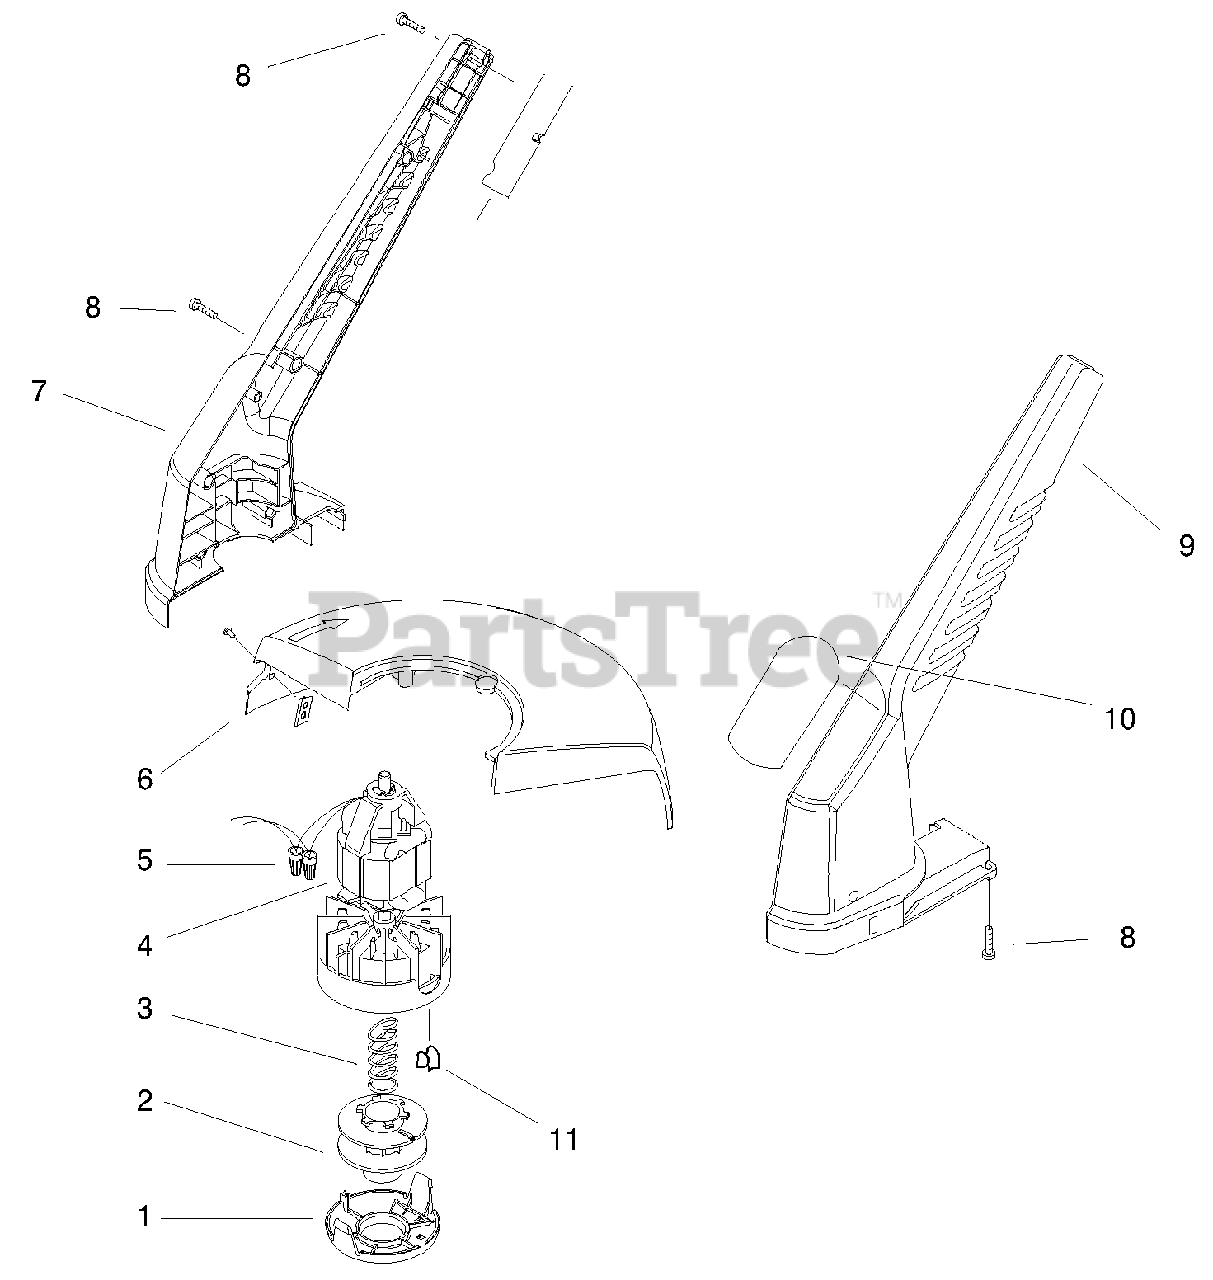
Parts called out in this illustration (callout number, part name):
2	Spool-Large
3	Spring-Compression
4	ASM-Motor,Drum-ervice
5	Connector-Wire Nut
6	Shield ASM-Service
7	Housing-RH (Black)
8	Screw-PPH
9	Housing-LH (Black)
10	Decal-15" Trim 'n Edge
